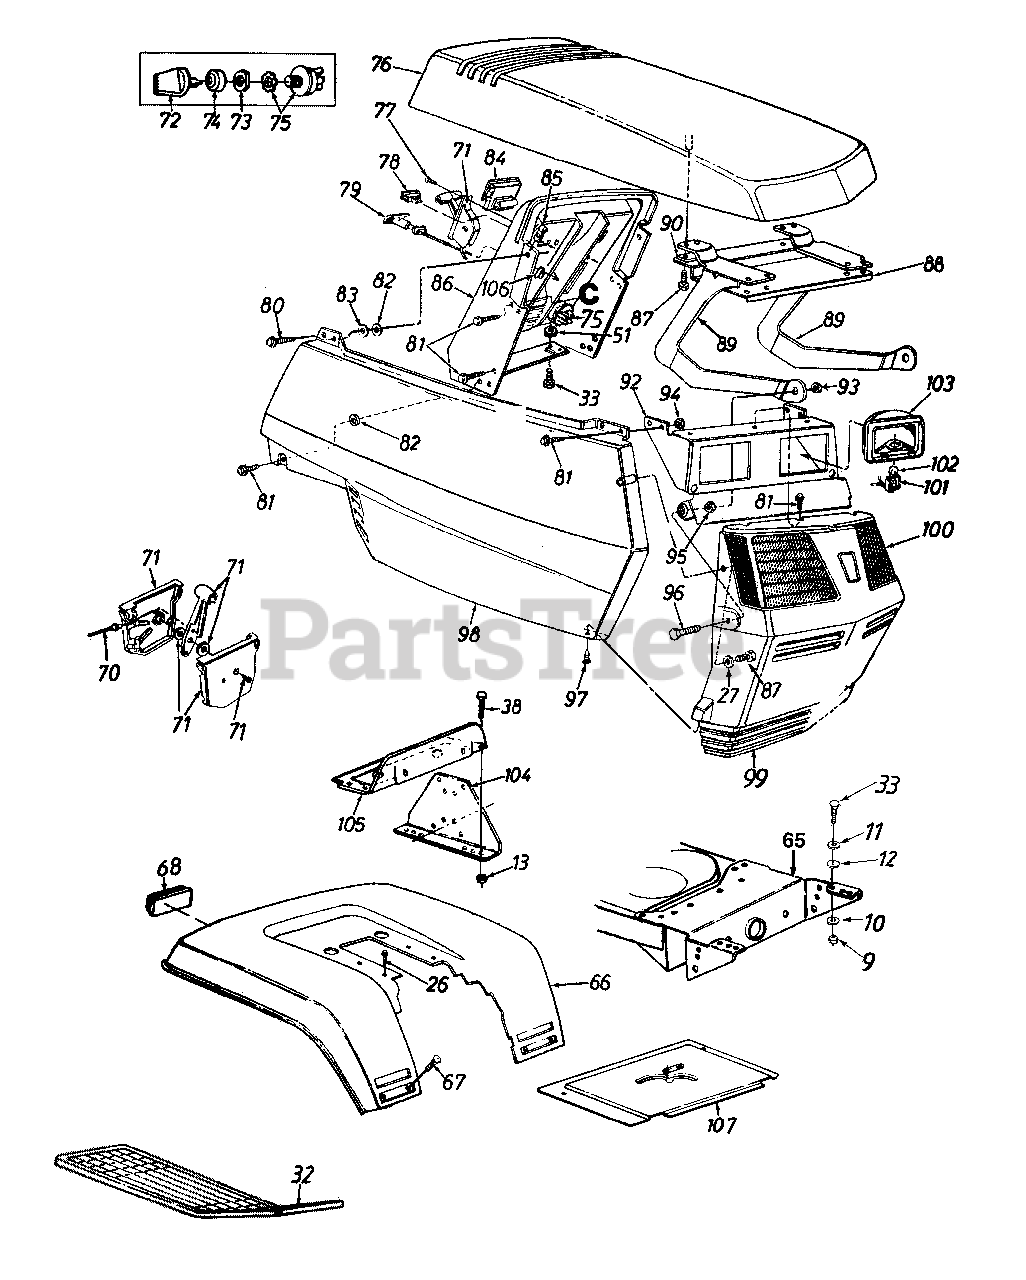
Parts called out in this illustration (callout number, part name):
9	Hex Nut 5/16-18 Thd.
10	L-Wash. 5/16" I.D.
11	Fl-Wash. .34" I.D. x 1" O.D.
12	Speed Nut
13	Hex Sems Nut 1/4-20 Thd.
26	Hex Wash. Hd. AB-Tap Scr.5/16 x .75" Lg.
27	Fl-Wash. .218" I.D. x .5" O.D.
32	Rubber Foot Pad L.H.
33	Hex Bolt 5/16-18 x .75" Lg.
38	Hex Bolt 1/4-20 x .62" Lg.
51	Hex Sems Nut 5/16-18 Thd.
68	Reflector
70	Throttle Wire 18.5" Lg.
71	Throttle Control Box Ass'y.
72	Ignition Key
73	Ignition Switch Nut
74	Ignition Switch Cap
75	Ignition Switch
76	Hood
77	Truss Mach. AB-Tap Scr. #10 x.5" Lg.
78	Light Switch
79	Choke Control 29" Lg.
80	Hex Wash. Hd. Tap Scr.1/4 x .75"
81	Hex Tap Scr. 1/4-20 x .5" Lg.
82	Push Nut Fastener
83	Fl-Wash. .27" I.D. x .948"
84	Ammeter
85	Speed Nut 1/4-20 Thd.
86	Dash Panel
87	Hex Wash. Hd. B-Tap Scr.1/4 x .75" Lg.
94	Hex L-Nut 1/4-20 Thd.
95	Hex Jam Nut 5/16-18 Thd.
96	Hex Bolt 5/16-18 x 7/8" Lg.
97	Truss Mach. B-Tap Scr.#10 x .5" Lg.
98	Side Cover-R.H.
99	Grille
100	Lens-L.H.
101	Twist Lock-Lamp Socket
102	Lamp
103	Headlight Housing
